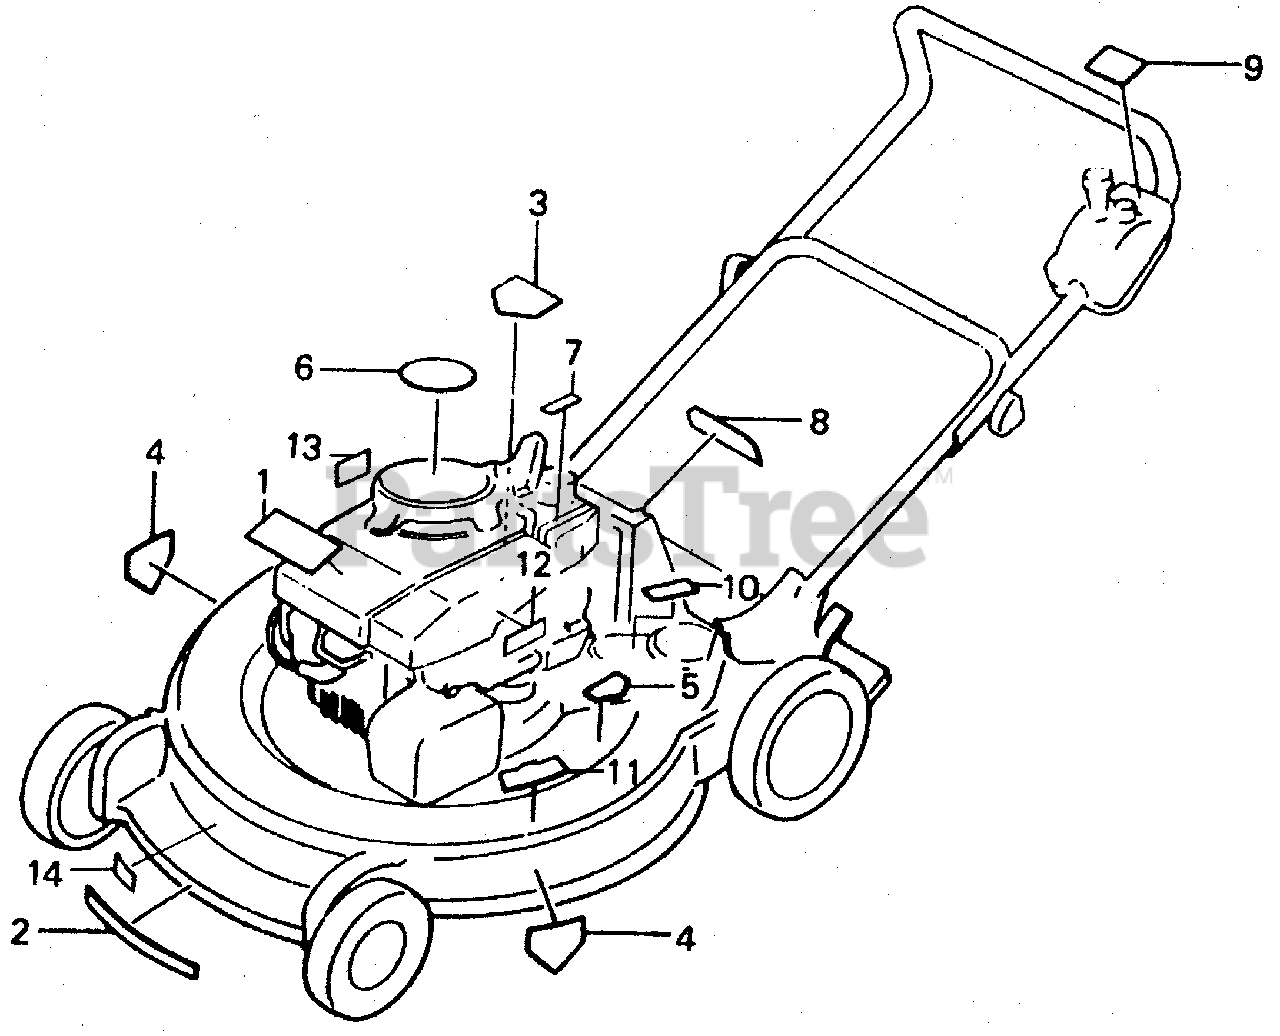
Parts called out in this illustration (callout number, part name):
1	MARK, TOP COVER (NOT AVAILABLE)
2	LABEL A, HOUSING CAUTION (ENGLISH)
3	CAUTION C, HOUSING
4	LABEL B, HOUSING CAUTION
5	LABEL, STEP POSITION (ENGLISH) (NOT AVAILABLE)
6	CAUTION, OPERATOR (ENGLISH) (NOT AVAILABLE)
7	LABEL, FUEL CAUTION (ENGLISH)
8	LABEL, DISCHARGE GUARD CAUTION (NOT AVAILABLE)
9	LABEL, CONTROL COVER CAUTION (ENGLISH) (NOT AVAILABLE)
10	CAUTION, BELT COVER (ENGLISH) (NOT AVAILABLE)
11	LABEL, PLUG CAUTION (ENGLISH)
12	MARK, AIR CLEANER CAUTION (NOT AVAILABLE)
13	MARK, OIL CAUTION (NOT AVAILABLE)
